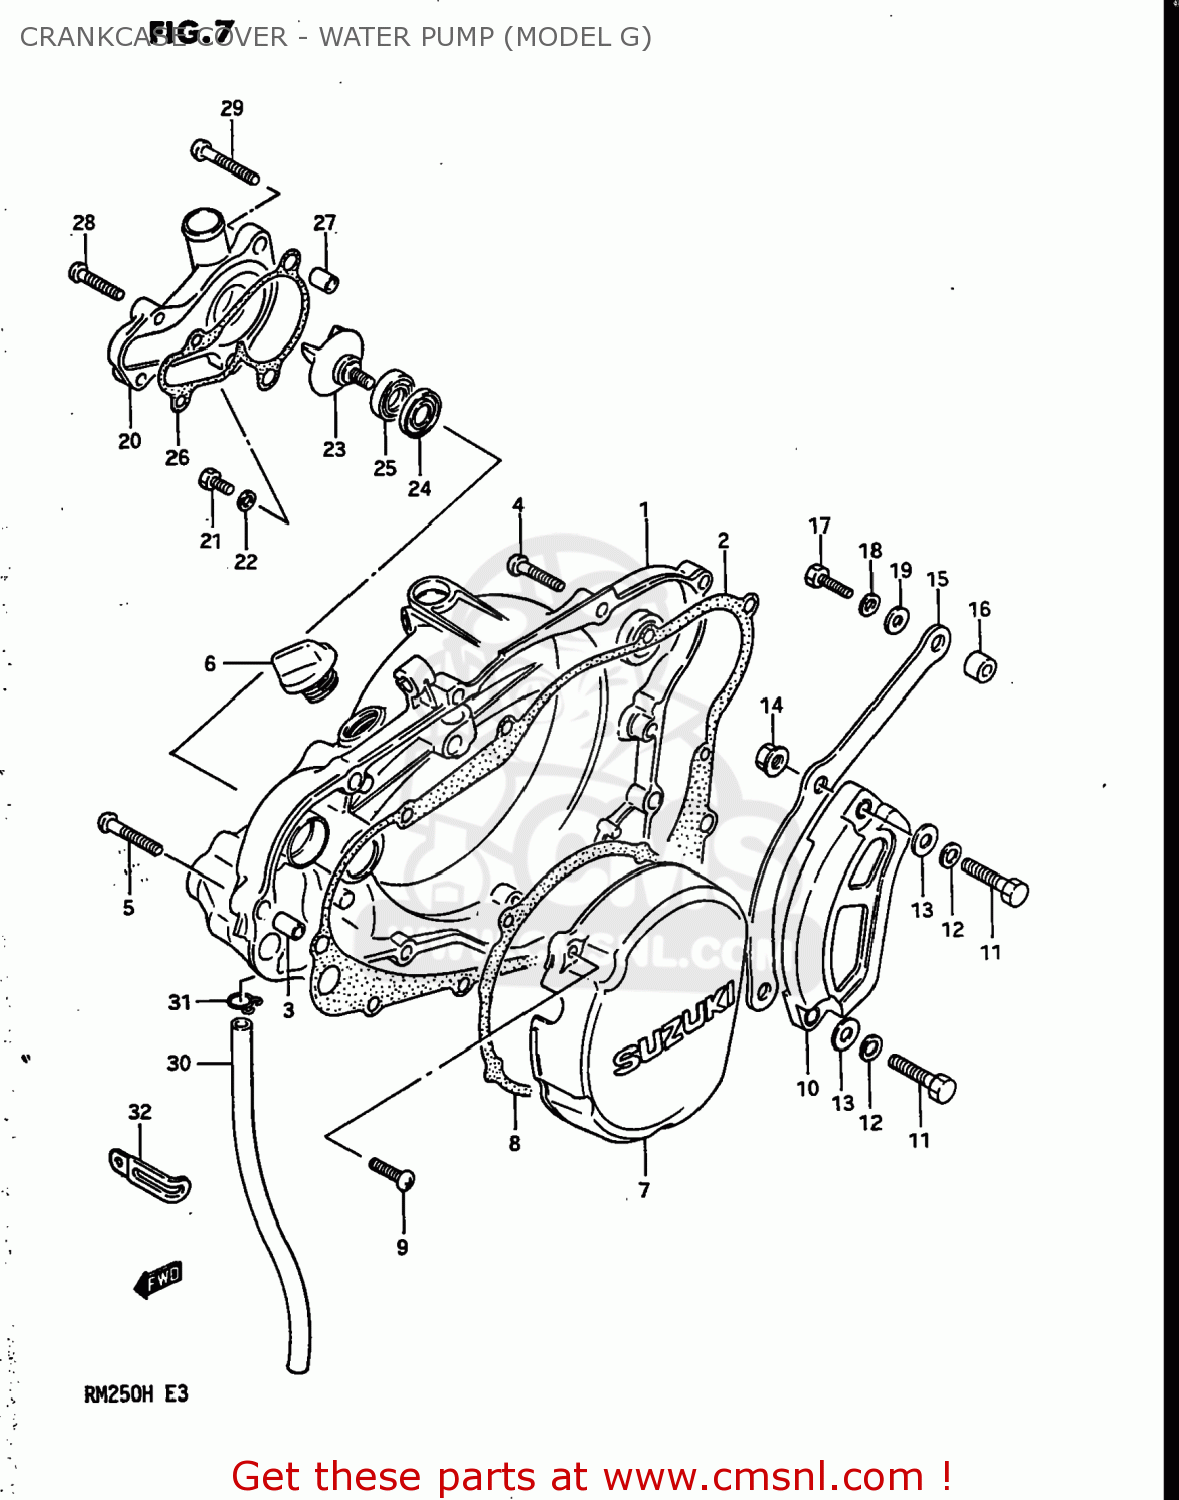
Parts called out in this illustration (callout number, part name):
1	COVER SET,CLUTCH
2	GASKET,CRANKCASE (MCA)
3	PIN
4	SCREW
5	SCREW (6X35)
6	PLUG SET
7	COVER,MAGNETO
8	GASKET,MAGNETO COVER (MCA)
9	SCREW
10	COVER,SPROCKET
11	BOLT (8X30)
12	LOCK WASHER
13	WASHER
14	NUT
15	PLATE,FRONT CHAIN GUIDE
16	SPACER (6.5X12X8)
17	BOLT
18	WASHER,LOCK
19	WASHER
20	CASE COMP,WATER PUMP
21	BOLT,BLEEDER
22	GASKET (NAS)
23	IMPELLER,WATER PUMP
24	SEAL,OIL(12X24X7)
25	SEAL,OIL(12X24X6.4)
26	GASKET,WATER PUMP CASE (MCA)
27	PIN
28	SCREW
29	SCREW 6X30
30	HOSE
31	CLIP
32	CLAMP
